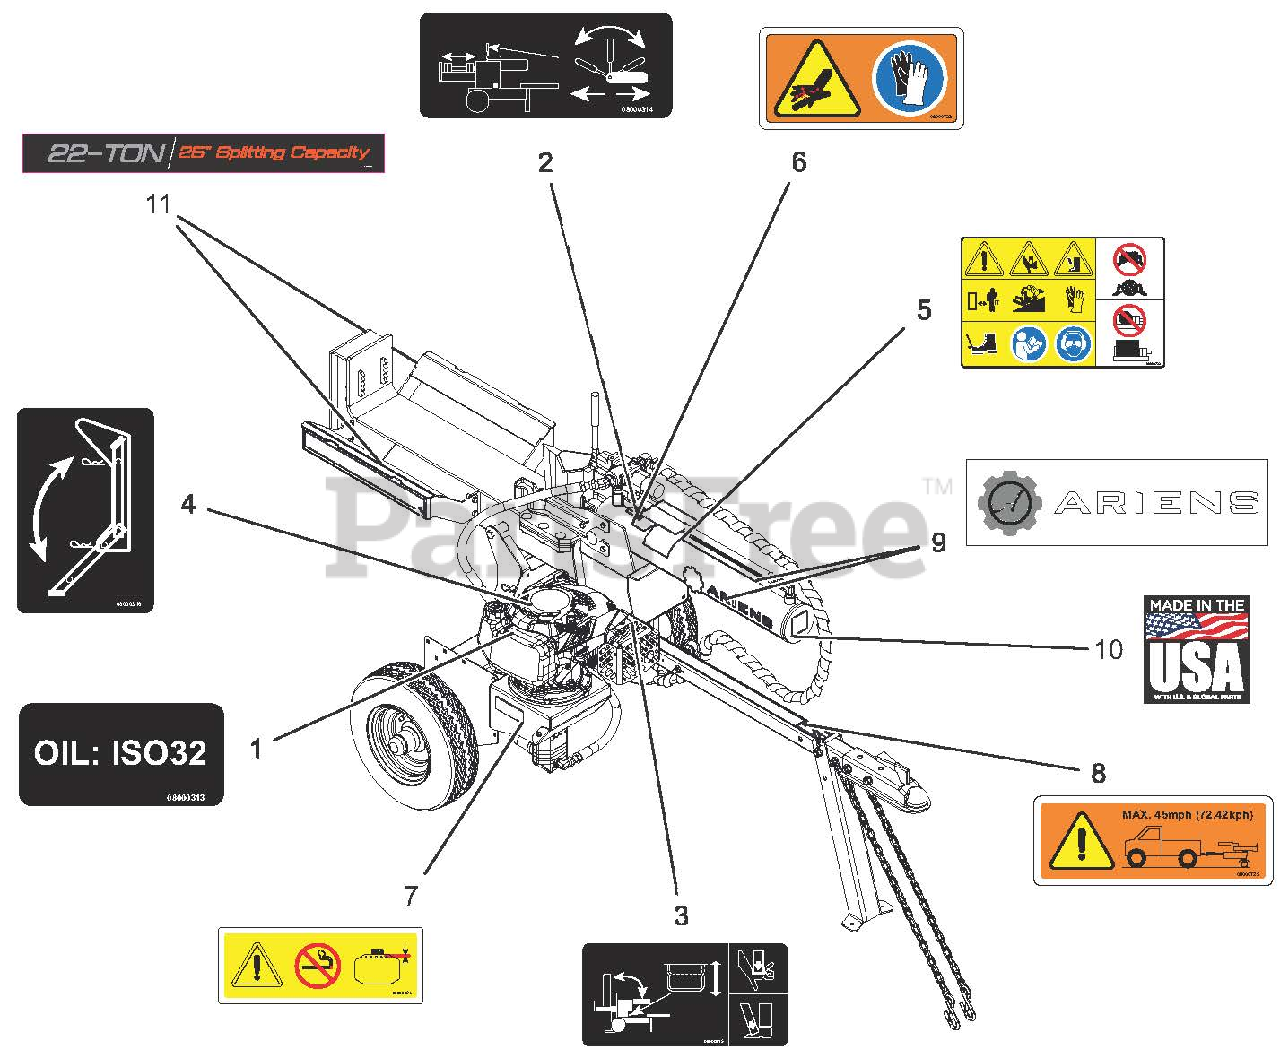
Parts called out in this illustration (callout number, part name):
1	DECAL, LOG SPLITTER-HYD OIL
2	DECAL, LOG SPLITTER-RAM OP
3	DECAL, LOG SPLITTER-TILT OP
4	DECAL, LOG SPLITTER-REAR STAND
5	DECAL,DANGER LOG SPLITTER
6	DECAL,HYD WARNING
7	DECAL,FUEL WARNING
8	DECAL,TOWING
9	DECAL-ARIENS-CYLINDER
10	DECAL, MADE IN USA
11	DECAL-CRADLE-22 TON
